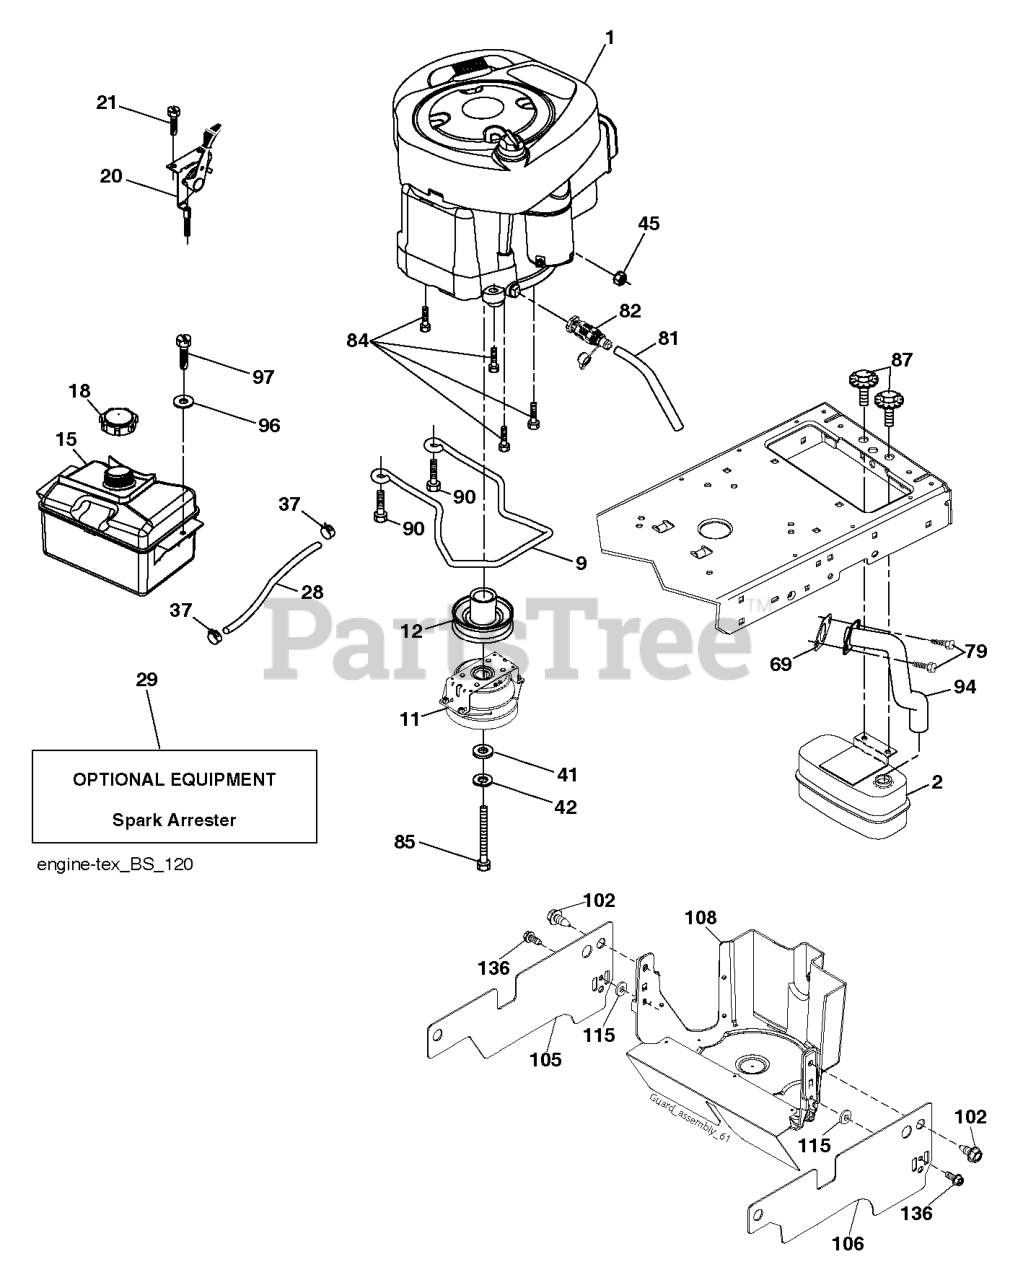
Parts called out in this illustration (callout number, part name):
2	MUFFLER.SINGLE.CYL.KOHL/B&S
9	KEEPER.BELT.ENG.4.25"2.BLT.431
11	CLUTCH.OGURA.4.4PD.GT1.5-EH13V
12	PULLEY.ENGINE.TUFFTORQ
15	RP TANK FUEL FRT 1.5 GAL
18	CAP ASM.FUEL.2.25"FR.
20	THROTTLE.COBRA.21".RSTART.BLK
21	SCREW.#10 X 0.750.BOS
28	LINE.FUEL.20
29	KIT.SPARK ARRESTOR 794945 B&S
37	HOSE CLAMP
42	WASHER 7/16 LOCK
45	NUT
69	REPL BY 532 27 22-93
79	SCREW.SOCKET HD.5/16-1
81	TUBE, DRAIN OIL ASM.
82	VALUE.OIL.DRAIN
84	SCREW.3/8-16
85	CLUTCH BOLT7/16-20X3.5 GR524HR
87	BOLT.5/16-18UNCX3/4 W/SEMS.BLK
90	SCREW 3/8-16X1
94	EXHAUST.TUBE.B&S.28/31
96	WASHER
97	SCREW HEXWSHR 1/4-20X3/4
102	SCREW
105	SHIELD.SIDE.LH.3842"TEX FRN.BK
106	SHIELD.SIDE.LH.3842"TEX FRN.BK
108	COVER ENGINE PULLEY COVER WITH
136	SCREW.#10 X 0.500
